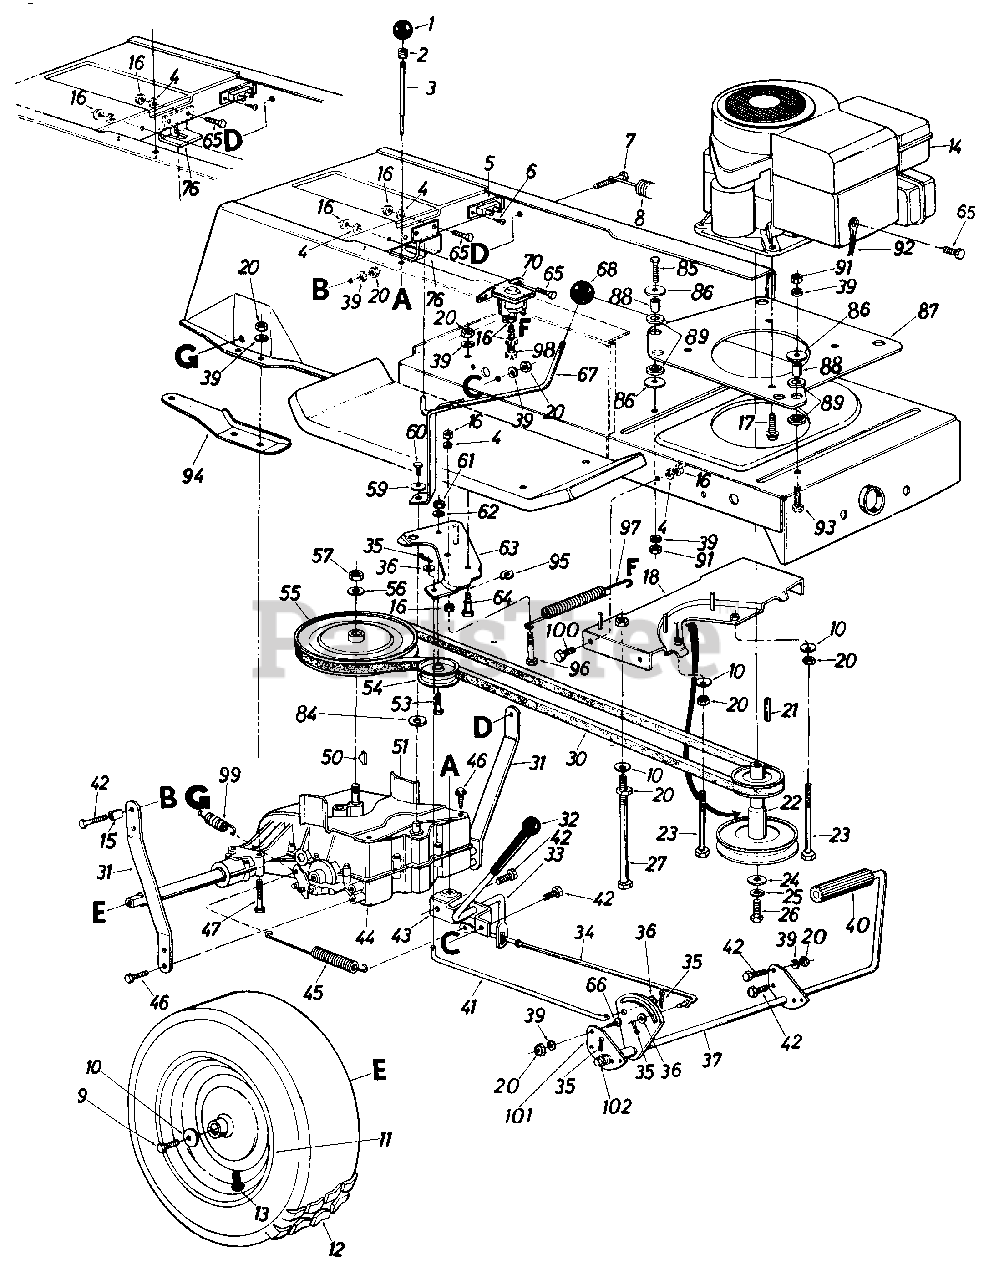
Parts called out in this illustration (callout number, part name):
1	Ball Knob 1/4-20 Thd.
2	Compression Spring .30" O.D. x 1.00" Lg.
3	Brake Lockout Rod
4	L-Wash. 1/41' I.D.*
5	Circuit Breaker
6	Truss Hd. Phil. Scr. #10 x 1/2" Lg
7	Hex Bolt 5/16-18 x 1.25" Lg.
8	Ext. Spring .99" O.D. x 11"
9	Hex Bolt 5/16-24 x .75" Lg.*
10	Bell-Wash. 5/16" I.D.
11	Rear Wheel Rim Only
12	Rear Wheel Ass'y. Comp.
13	Air Valve
14	Engine
15	Bushing
16	Hex Nut 1/4-20 Thd.*
17	Hex Bolt 3/8-16 x 1.25" Lg.
18	Belt Guard Brkt. Ass'y.
20	Hex Nut 5/16-18 Thd.*
21	Sq. Key 1/4" x 1/4" x 2.0"
22	Two Step Engine Pulley
23	Hex Bolt 5/16-18 x 5.25" Lg.
24	Fl-Wash. 7/16" I.D. x 1.25" O.D. x .180
25	L-Wash. 7116" I.D.*
26	Hex Bolt 7/16-20 x 1.50" Lg.
27	Hex Bolt 5/16-18 x 5.25"*
30	"V"-Belt "A" Glass 85" Lg.
31	Transaxle Brace
32	Grip
33	Hill Holder Brake Handle
34	Brake Rod
35	Cotter Pin 3/32" Dia. x 1.0"*
36	Fl-Wash. .344" I.D. x .625"
37	Brake/Clutch Pedal Ass'y
39	L-Wash. 5/16" I.D.*
40	Foot Pedal Pad
41	Clutch Rod
42	Hex Bolt 5/16-18 x .75" Lg.*
43	Brake Lock and Handle
44	Transaxle Complete
45	Ext. Spring .590" O.D. x 7.08" Lg.
46	Hex Wash. Hd. AB-Tap Scr. 5/16 x .62" Lg.
47	Hex Bolt 5/16-18 x 2.50"
50	#4 Hi-Pro Key 3/32 x 518" Dia.
51	Belt Keeper
53	Hex Bolt 3/8-16 x 1.50" Lg.
54	Flat Idler Pulley 3/8" I.D. x 2.75 O.D.
55	Transaxle Pulley
56	L-Wash. 1/2" I.D.
57	Hex Nut 1/2-20 Thd.
59	Bell-Wash. .26" I.D. x .75"
60	Hex Bolt 1/4-28 x .62" Lg.
61	Hex Nut 3/8-16 Thd.
62	L-Wash. 3/8" I.D.
63	Idler Brkt. Ass'y
64	Shld. Scr. .437" Dia. x 1.80" Lg. (5/16-18)
65	Hex Bolt 1/4-20 x .62" Lg.*
67	Shift Lever Ass'y
68	Ball Knob 3/8-16 Thd.
70	Solenoid
76	Shift Lever Pivot Brkt.
84	Special Wash. 1.00" O.D.
85	Hex Bolt 5/16-24 x 1.25"
86	Fl-Wash. 1.25" O.D. x .320" I.D.
87	Engine Mounting Plate
88	Spacer
89	Engine Mounting Grommet
91	Hex Nut 5/16-24 Thd.
92	Electric Ground Wire
93	Hex Bolt 5/16-24 x 1.50"
94	Transaxle Support Brkt.-R.H.
95	Wave Wash.
96	Hex Bolt 1/4-20 x 2.50" Lg.*
97	Ext. Spring
98	Hex Bolt 1/4-20 x 2.50" Lg.
99	Brake Return Spring
100	Hex Bolt 1/4-28 x .75" Lg. (Grade 5)
101	Pedal Bracket
102	Fl-Wash. .63" I.D. x 1.0" O.D.
